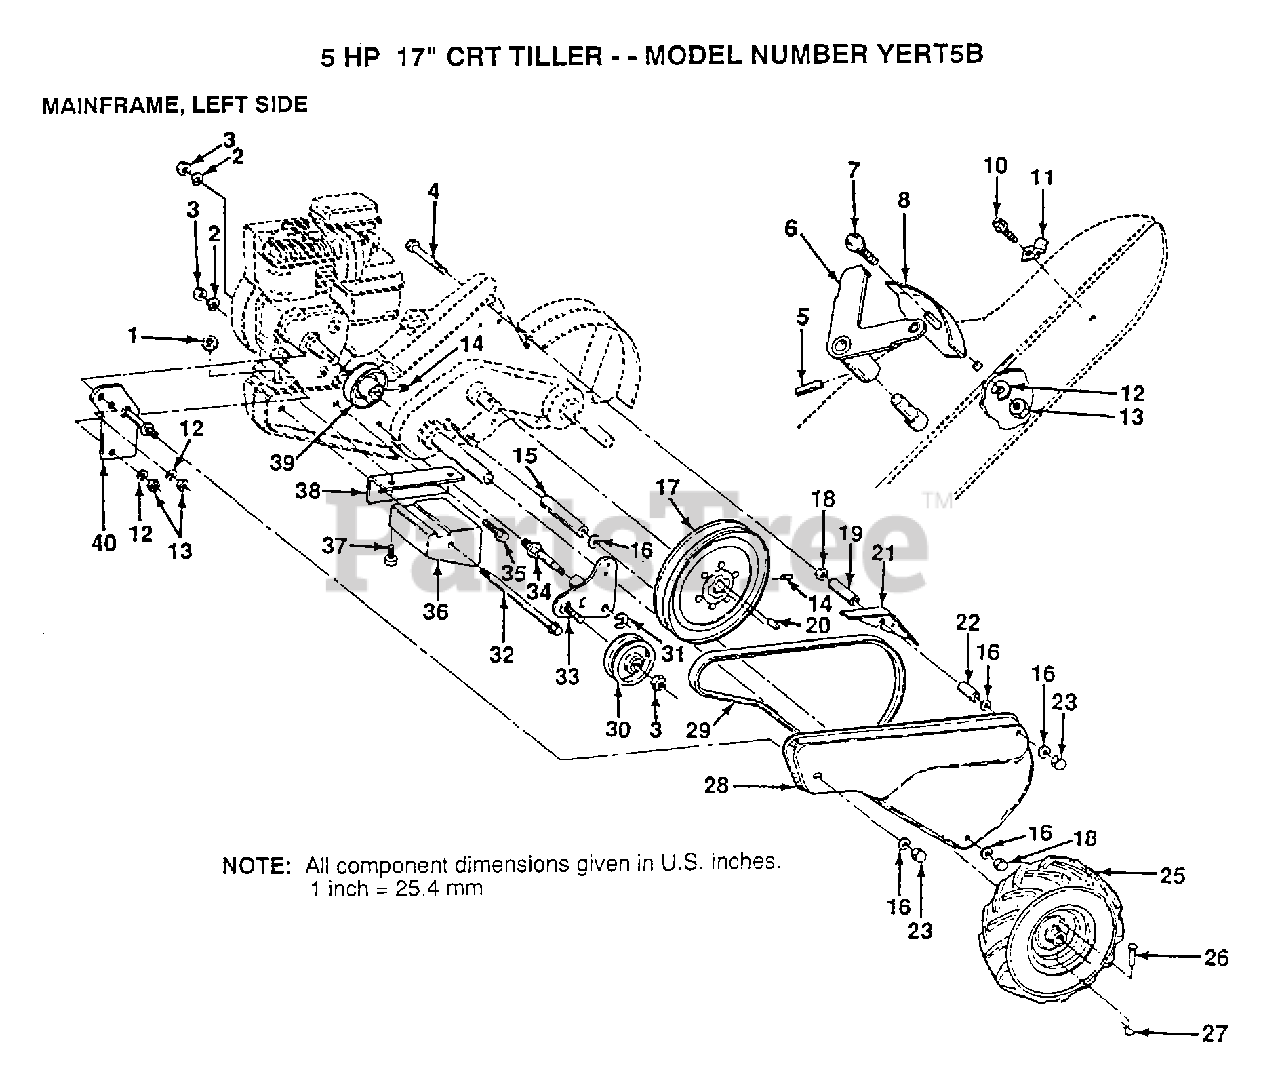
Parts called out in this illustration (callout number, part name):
2	LOCKWASHER
3	NUT.HEX.3/8-16UNC
4	BOLT-HEX TI
6	LEVER ASM CRT
7	BOLT
8	PANEL TI
11	CONDIUT CLIP T
12	LOCKWASHER
14	SET SCREW
15	WASHER
17	"SHEAVE 10"" CRT"
18	NUT.HEX.5/16-18
19	SPACER CRT
20	KEY T
21	GUARD CRT
22	SPACER CRT
23	NUT TI
24	TIRE.CHV.13X5.0-6
26	RIVET.DRILL.1.75
27	RETAINER M
30	PULLEY-IDLER TI
31	KLIP RING
32	BOLT CRT
34	SHIFT ARM CRT
35	BOLT
36	COUNTERWEIGHT CRT
37	BOLT.HEX.5/16-1.5
38	BRACKET LH CRT
40	BRACKET ASSY CRT
